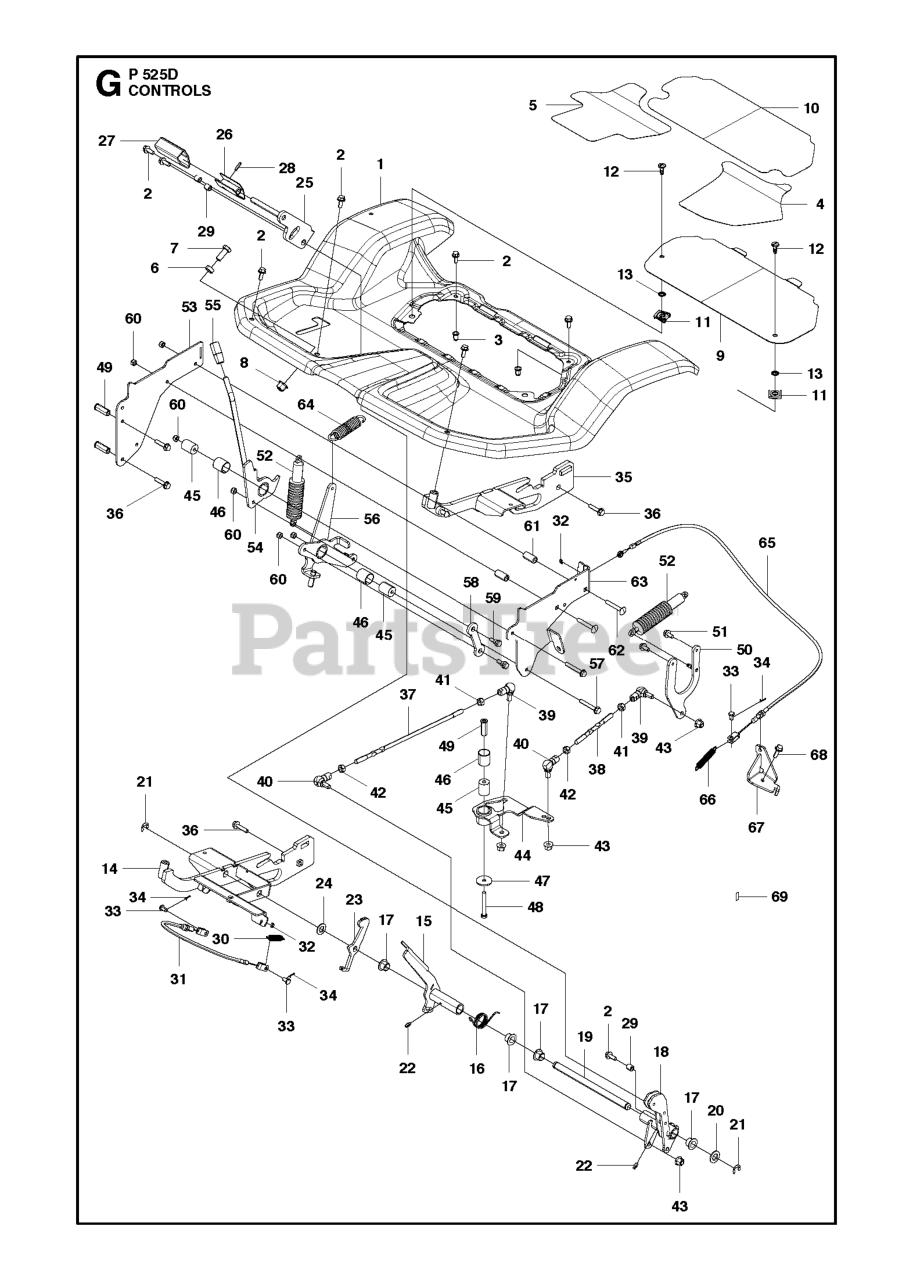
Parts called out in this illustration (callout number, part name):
7	Hex Head Capscrew, M12 X 1.75 X 30 DIN933ZP
17	BUSHING
22	GREASE NIPPLE
24	WASHER - M12
27	PEDAL RUBBER
33	Clevis Pin
34	Cotter Pin
36	SCREW EHHFM
42	NUT
46	BUSHING
52	SHOCK ABSORBER
57	SCREW EHHFM
60	LOCKNUT M8
68	BOLT
